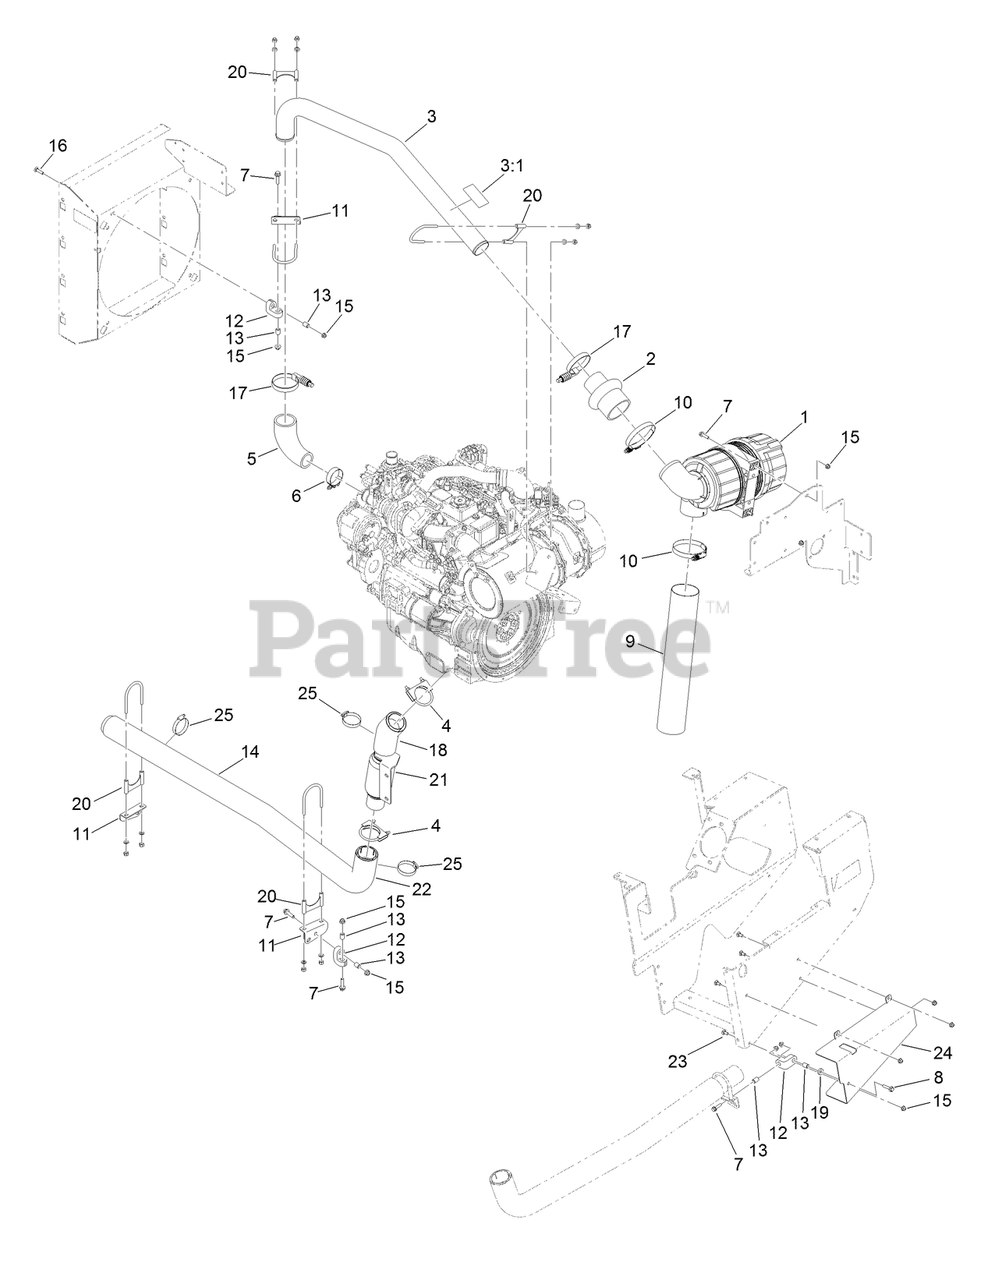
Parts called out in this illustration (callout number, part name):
1	AIR FILTER ASM
2	HOSE-HUMP
3	TUBE ASM-AIR INTAKE
3:1	DECAL-WARNING, HOT SURFACE
4	CLAMP-MUFFLER
6	CLAMP, T-BOLT
7	SCREW-HHF
8	SCREW-HHF
9	HOSE-INLET, AIR
10	CLAMP-HOSE
11	BRACKET-TUBE, INTAKE
12	HANGER-RUBBER
13	SPACER
14	WRAP-THERMAL, EXHAUST
15	NUT-HF, NI
16	SCREW-CARR
17	CLAMP-TORQUE, CONSTANT
18	WRAP-THERMAL, EXHAUST
20	CLAMP-GUILLOTINE
21	PIPE-EXHAUST
22	TUBE-EXHAUST
23	BOLT-CARR
24	GUARD-EXHAUST, LONG
25	CLAMP-HOSE
